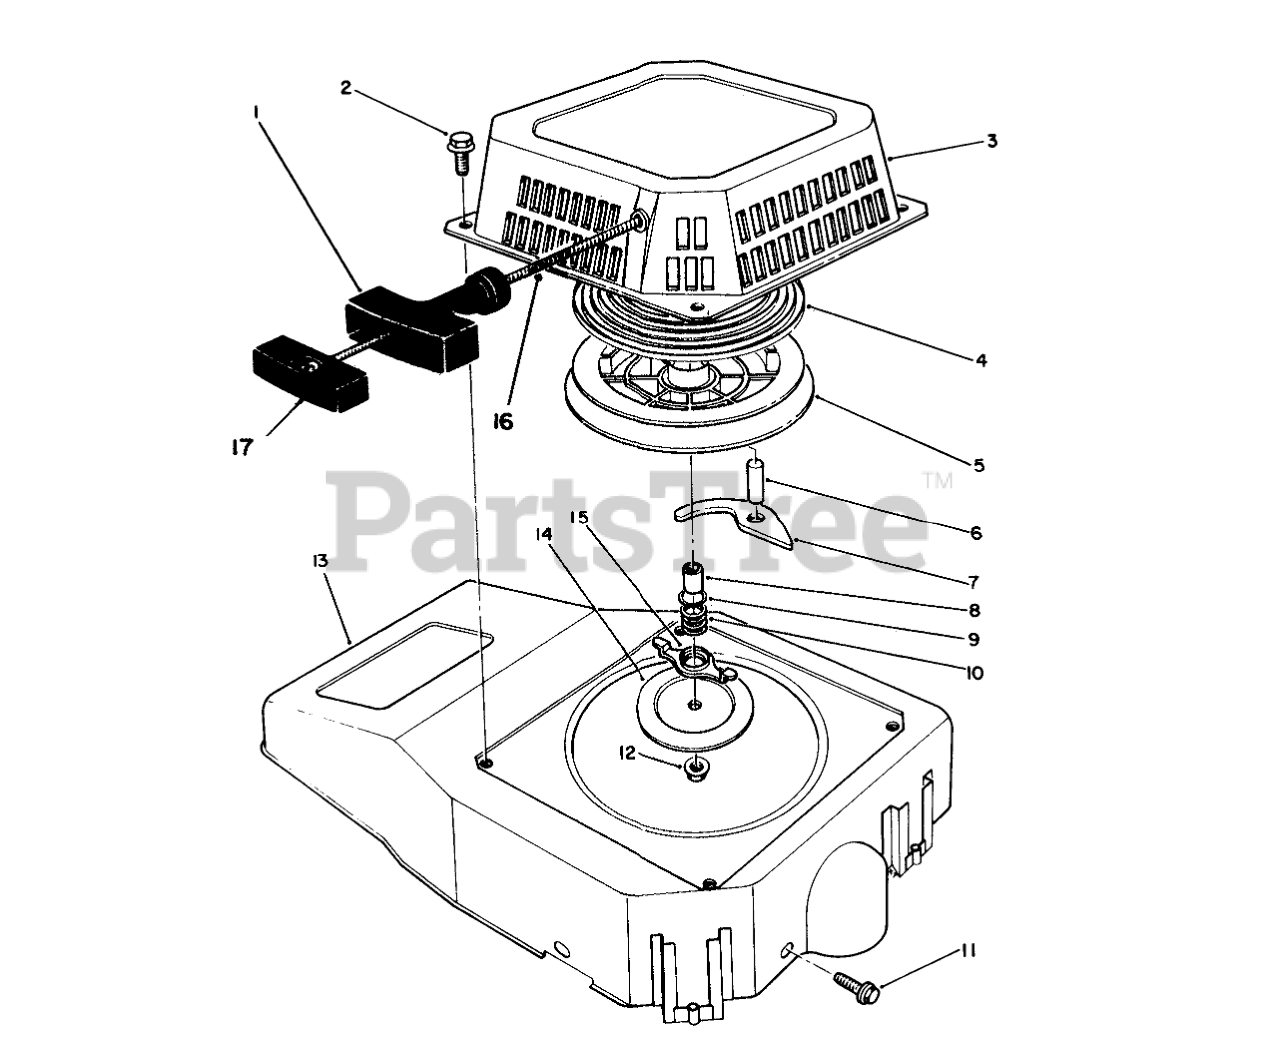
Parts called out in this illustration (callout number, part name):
1	HANDLE
2	SCREW-HHF
3	Case-Recoil
4	SPRING
8	Spacer
9	WASHER
10	Spring-Friction
13	SHROUD
14	PLATE
15	Guide-Paw
16	ROPE-STARTER
17	RETAINER HANDLE
